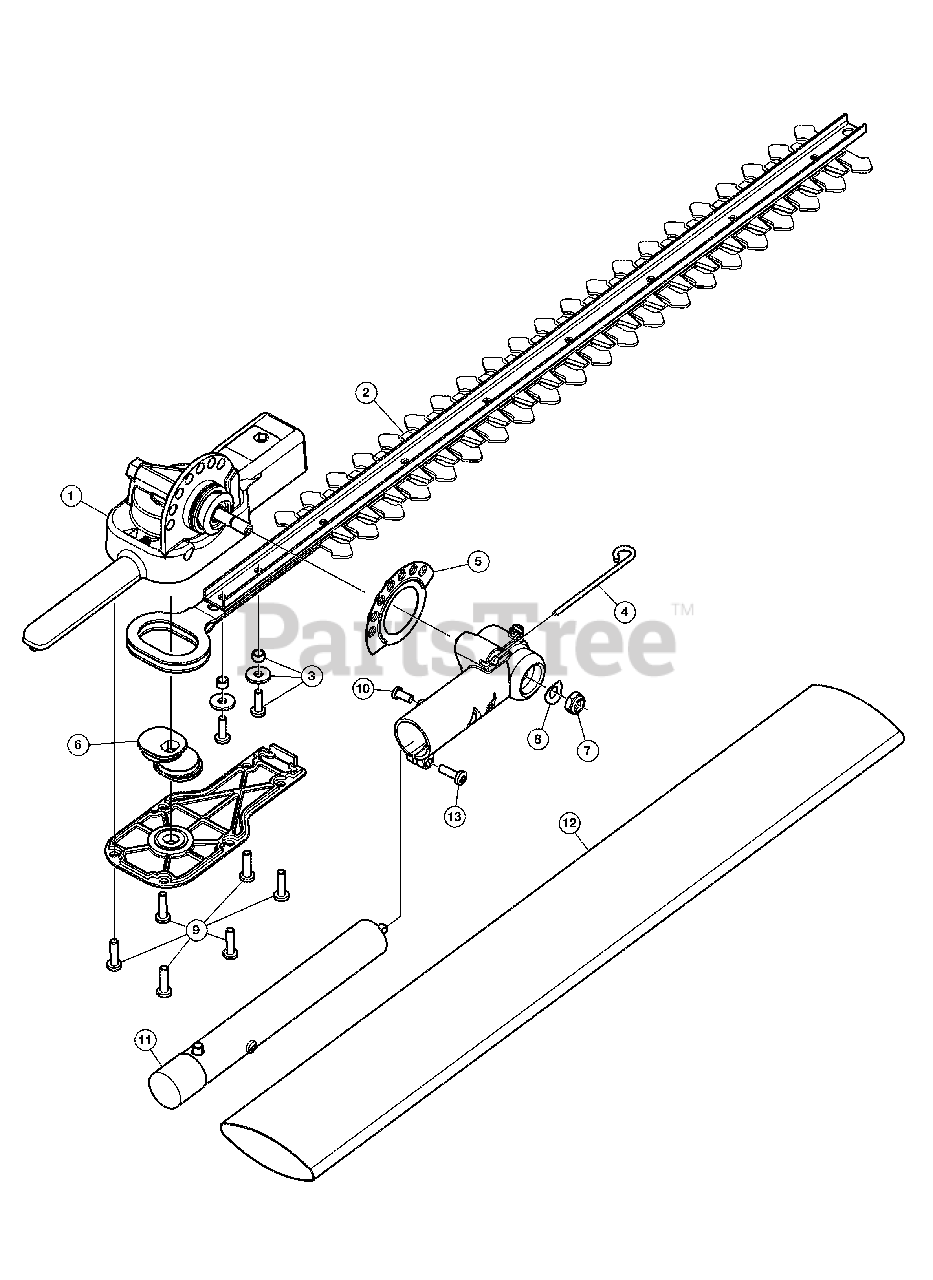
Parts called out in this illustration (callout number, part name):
1	Gearbox (Incl. 2 - 9)
2	Blade Assembly (Incl. 3)
3	Blade hardware
4	Locking Lever
8	Wavy Washer
10	Anti-Rotation Screw
11	Boom Assembly
12	Blade Guard
13	Screw
